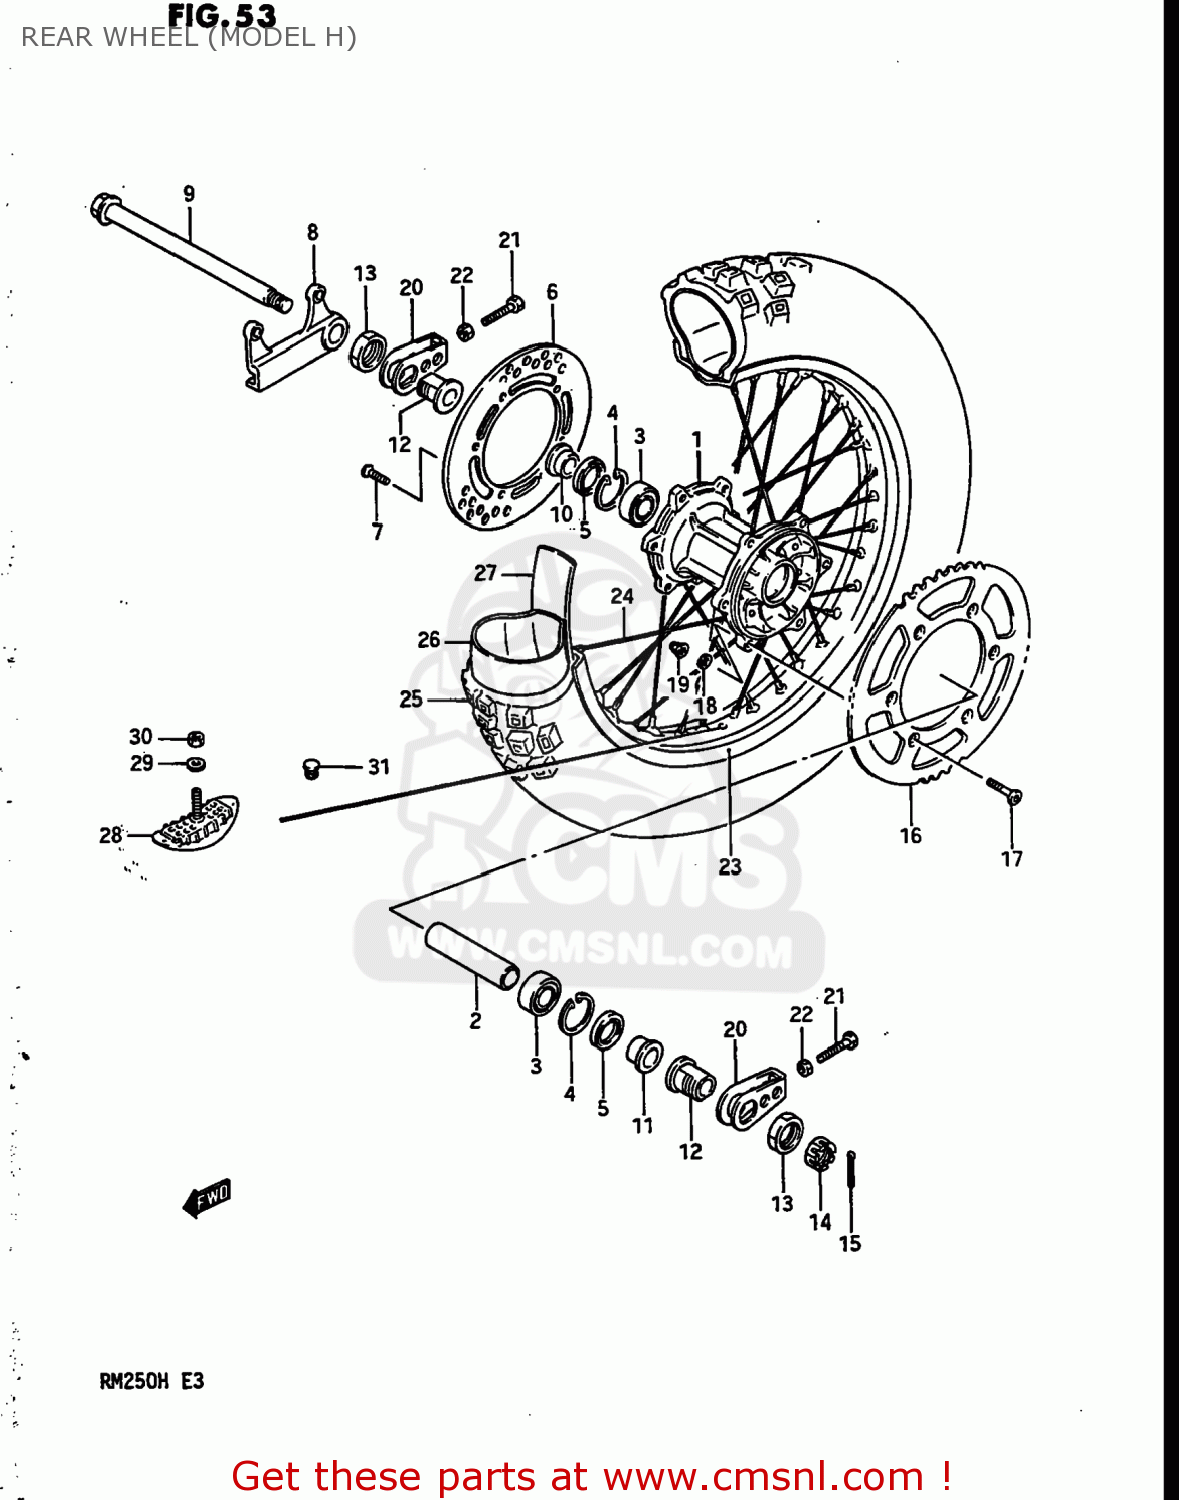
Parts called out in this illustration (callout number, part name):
1	HUB,REAR WHEEL
2	SPACER,BEARING
3	BEARING
4	CIRCLIP,14MM
5	OIL SEAL
6	DISC,REAR BRAKE
7	SCREW
8	BRACKET,REAR CALIPER
9	AXLE,REAR
10	SPACER,REAR AXLE
11	SPACER COMP,REAR AXLE
12	SPACER,CHAIN ADJUSTER
13	NUT
14	NUT 18MM
15	PIN,COTTER
16	SPROCKET,REAR
17	SCREW(8X33.5)
18	WASHER
19	NUT
20	ADJUSTER, CHAIN
21	BOLT(8X43)
22	NUT
23	RIM,REAR WHEEL
24	SPOKE SET,REAR WHEEL
25	TIRE
26	TUBE,INNER
27	PROTECTOR,WHEEL,INNER
28	STOPPER,BEAD
29	WASHER
30	NUT 8MM
31	CAP(OD:12)
